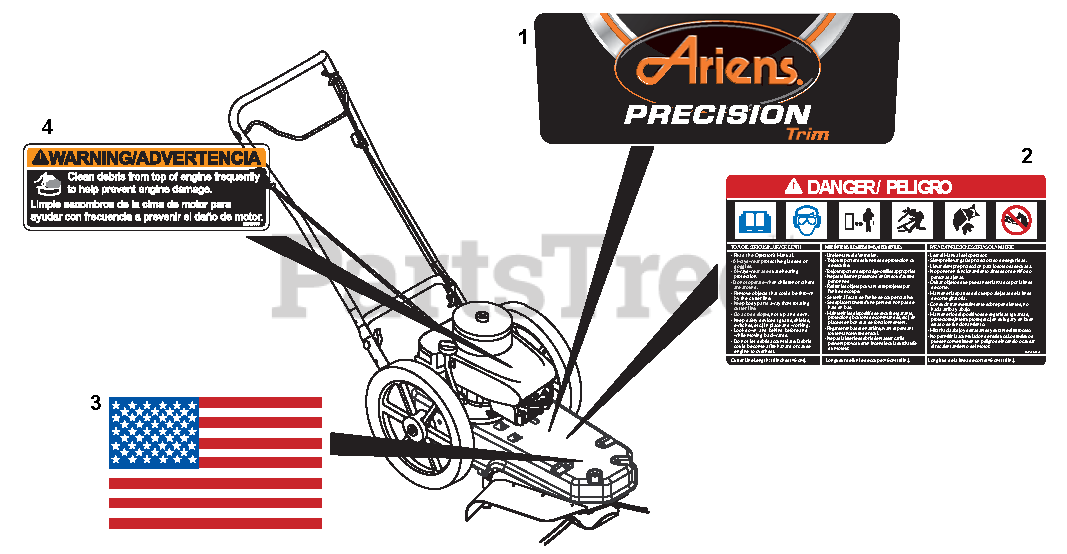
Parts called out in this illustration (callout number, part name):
1	DECAL, ARIENS PRECISION TRIM
2	DECAL - DANGER-STRING TRIMMER
3	DECAL, AMERICAN FLAG
4	DECAL, TRIMMER DEBRIS WARNING
